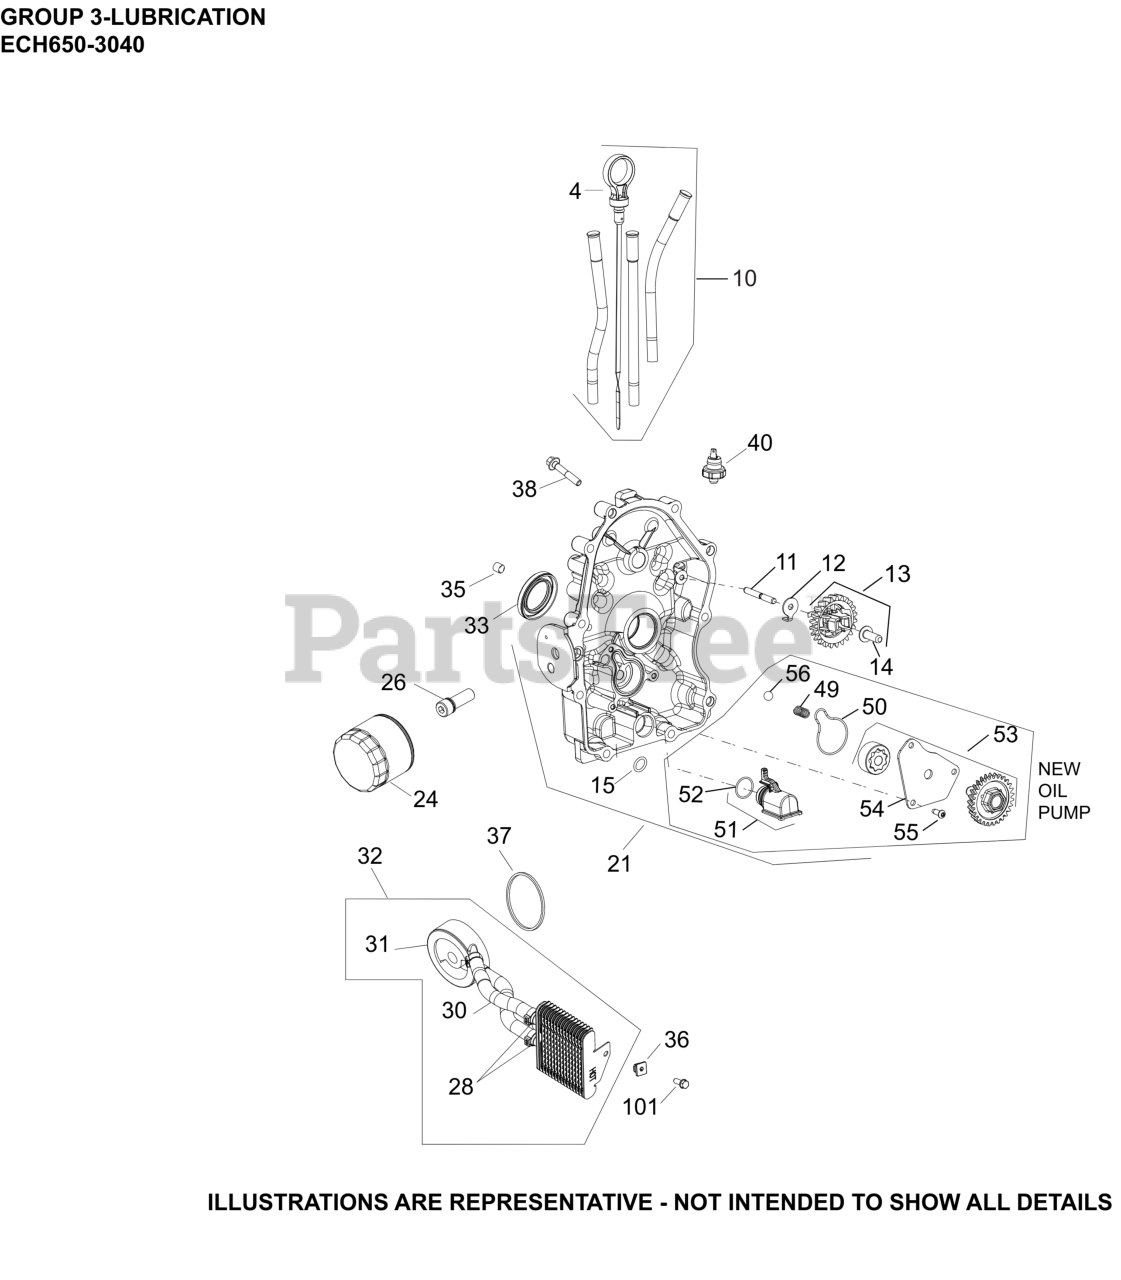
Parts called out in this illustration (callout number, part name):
10	KIT, DIPSTICK/DIPSTICK TUBES
11	SHAFT, GOVERNOR GEAR
12	TAB, LOCKING
13	KIT, GOVERNOR GEAR W/PIN
14	PIN, GOVERNOR REGULATING
21	KIT, CLOSURE PLATE ASSY
24	OIL FILTER
26	NIPPLE, OIL FILTER-USE 24 136 10-S
28	CLAMP, HOSE LOW PROFILE
30	KIT, HOSE 140MM
31	ADAPTER,OIL FILTER (CH EFI)-DISCONTINUED
32	COOLER, OIL & DIVERTER ASSEMBLY
35	PLUG, CTSK PIPE 1/8"
36	NUT, PLASTIC - BLACK
37	O-RING, OIL COOLER
38	SCREW, FLG M8X1.25X45
38	SCREW, HEX FLANGE
40	SENSOR, OIL PSI
49	SPRING, COMPRESSION
50	SEAL, OIL PUMP COVER
51	PICK-UP ASSEMBLY, OIL
52	O-RING, OIL PICK-UP
53	PUMP ASSEMBLY, OIL
54	COVER, OIL PUMP
55	SCREW, BUTTON HEAD-(#25086792S)
56	PRESSURE RELIEF BALL
NI	SCREW, HEX HEAD
